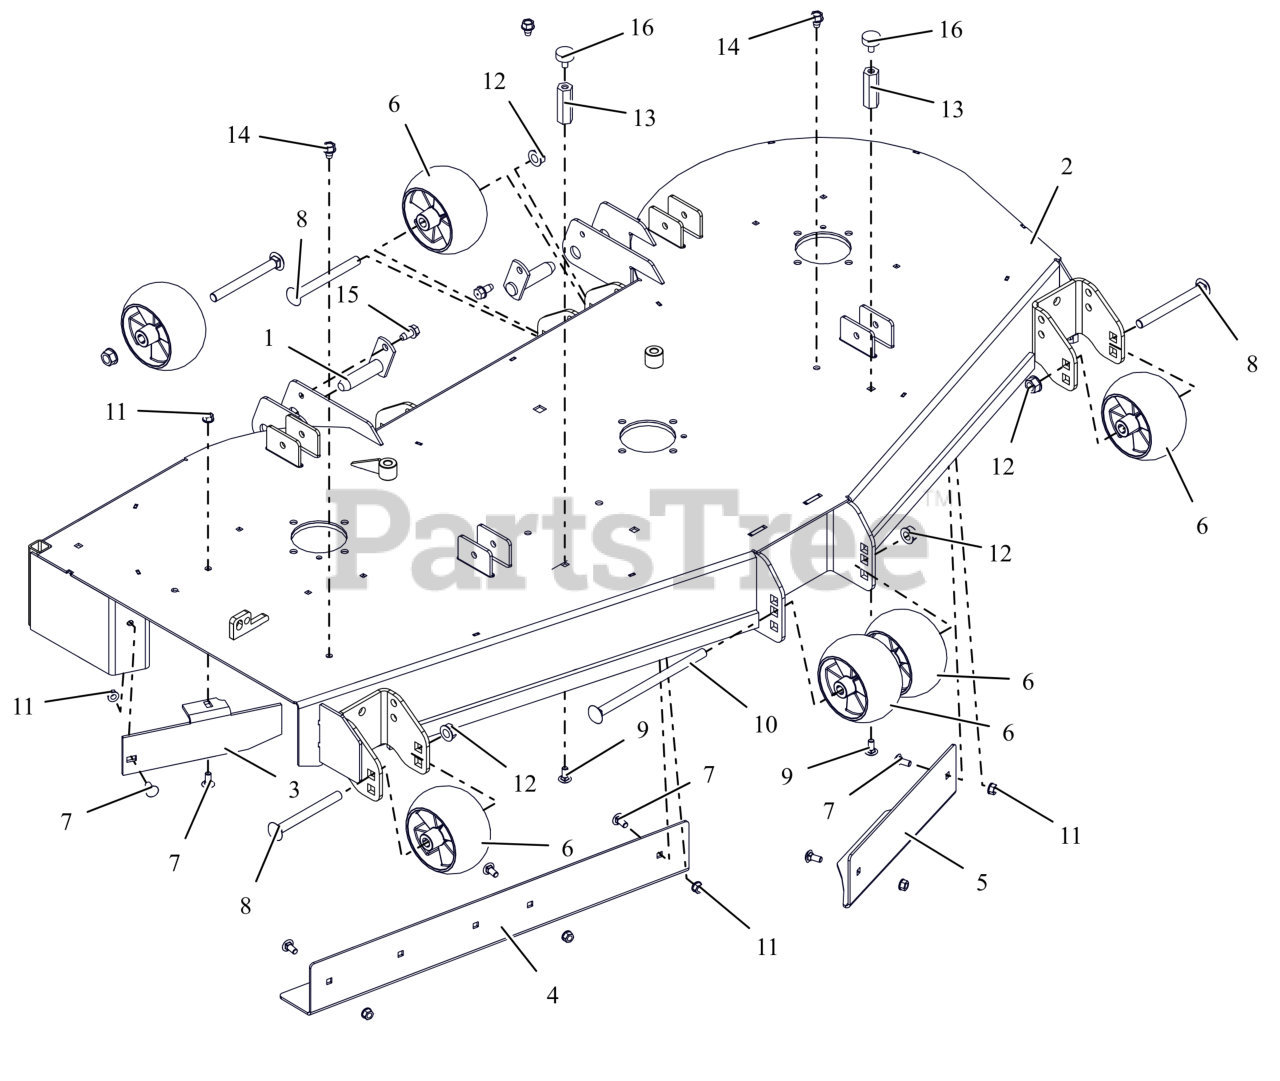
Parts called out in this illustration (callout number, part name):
1	WLDMT, MOWER MTG. PIN (BLACK)
2	KIT, 60" PRO-WALK DECK W/ DECALS (RED)
3	60" DISCHARGE BAFFLE - RED
4	BAFFLE, 60" RH VACUUM (RED)
5	BAFFLE, 60" LH VACUUM (RED)
6	WHEEL, ANTI SCALP - 5X3 CTR W/RIBS
7	BLT,RHSN .31-18X.75 G5 ZCC
8	BLT, RHSN .50-13X5.00 G5 ZCC
9	BTL,RHSN .313-18 X 0.75 G5 ZCC LT
10	BTL,RHSN .500-13 X 8.5S G5 ZCC
11	NUT,LK-CTR-FLG .31-18 GF ZCC
12	NUT-LK-CTR-FLG .500-13 GG ZCC
13	NUT, .31-18X2.25 LG COUPLING
14	SCR,TAP .375-16X.50 HWH TR ZCC
15	SCR,TAP .375-16X.75 HWH TR ZCC
16	BUMPER, RUBBER
